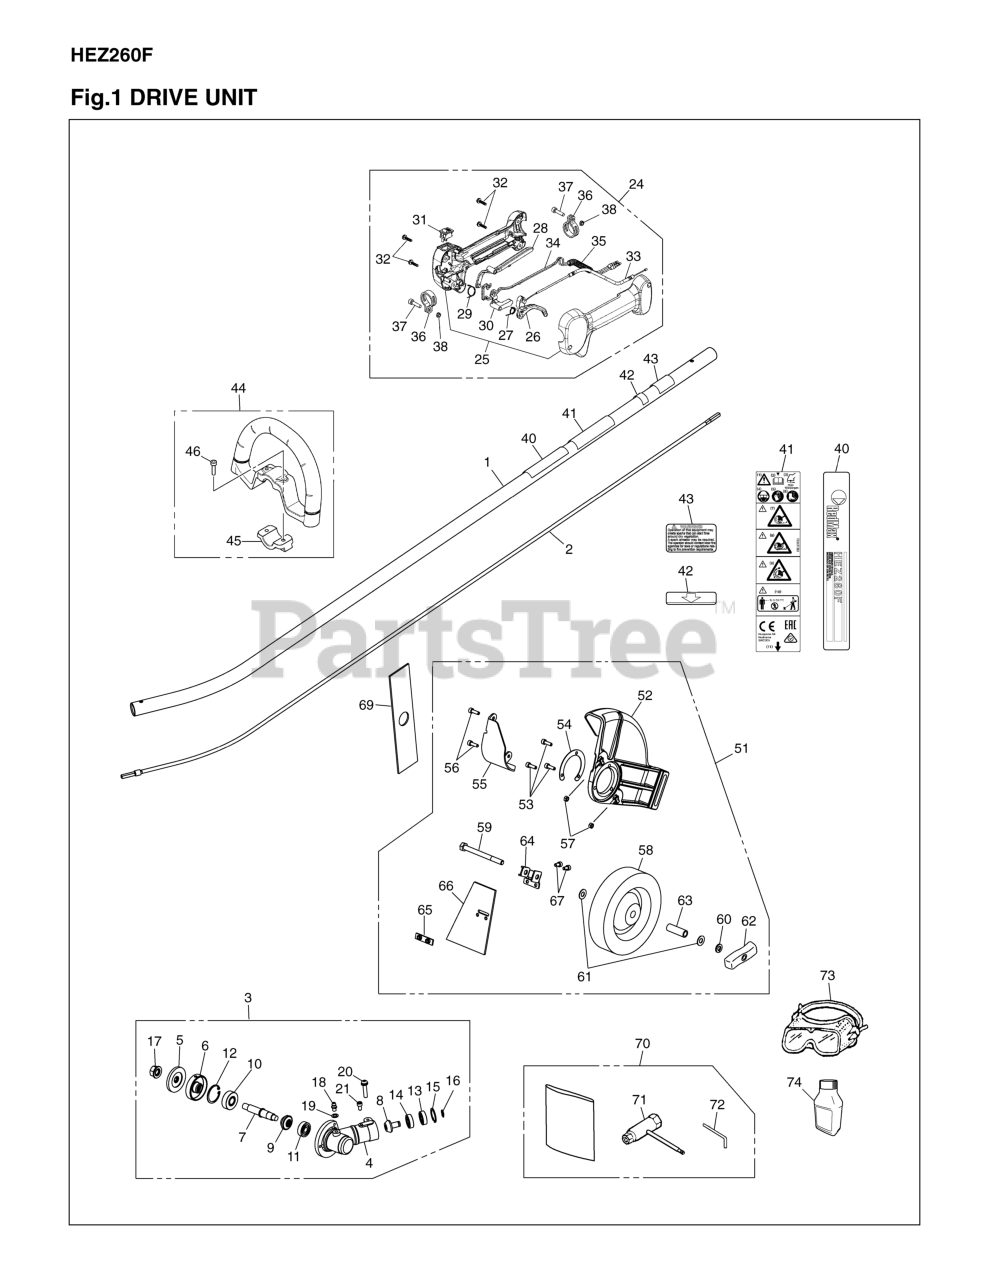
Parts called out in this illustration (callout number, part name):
1	PIPE COMP
2	FLEX SHAFT
3	GEARCASE ASSY
4	GEARCASE
5	HOLDER(B)
6	HOLDER(A)
7	SHAFT GEAR
10	BEARING***
24	ASSY THROTTLE
25	GRIP HALF SET
26	LEVER, THROTTLE
27	SPRING, THROTTLE
28	LEVER, SAFETY
30	LEVER JOINT
31	STOP SWITCH NM_09091801
34	CORD - C
38	NUT
43	DECAL SPARK ARRESTOR WARNING
44	HANDLE LOOP
45	CLAMP HANDLE
51	GUARD ASSY
52	GUARD
53	BOLT T27 M5X16
55	PLATE, PROTECTOR
70	TOOL SET
73	GOGGLExxx (RPLS
74	RM 48/2.6 OZ 2T OIL 50:1 (DS)
